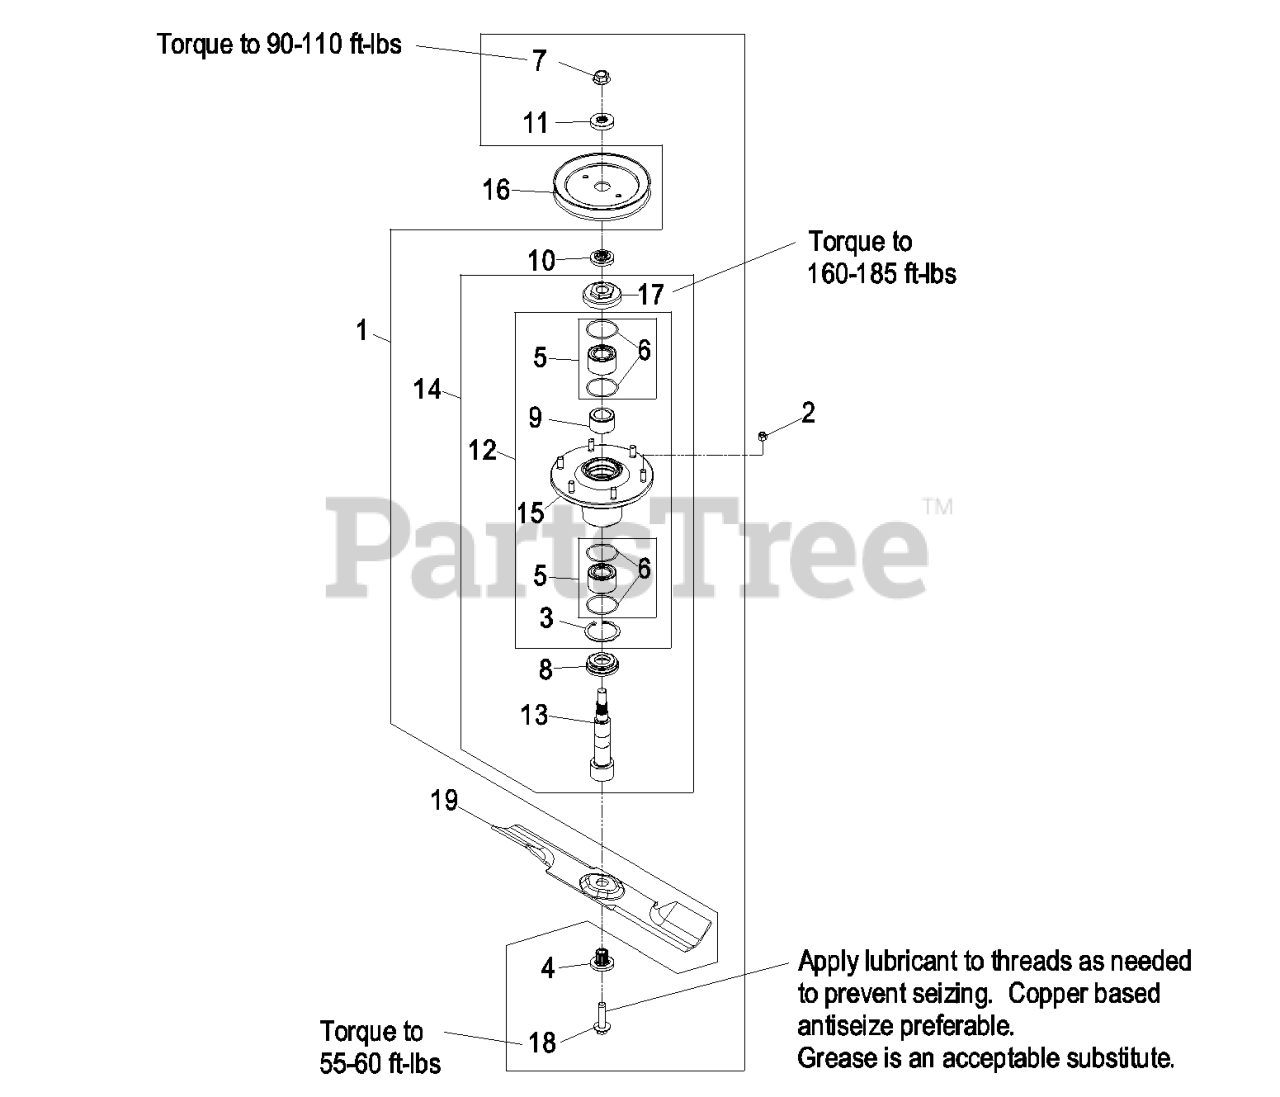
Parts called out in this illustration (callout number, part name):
1	ASM, CUTTER HSG W/MNT HRD
2	NUT-LOCK, NI
3	RING-RETAINING
4	BUSHING,SPLINED
5	ASM, BEARING W/ORINGS
7	NUT-FLANGE, CENTERLOCK
8	GUARD,BOTTOM
9	SPACER,BEARING
10	SPACER,SPLINED STEPPED
11	SPACER,SPLINED
12	ASM,CUTTER HOUSING
15	ASM,HOUSING W/STUDS
16	SHEAVE, BLADE DRIVE 6.13
